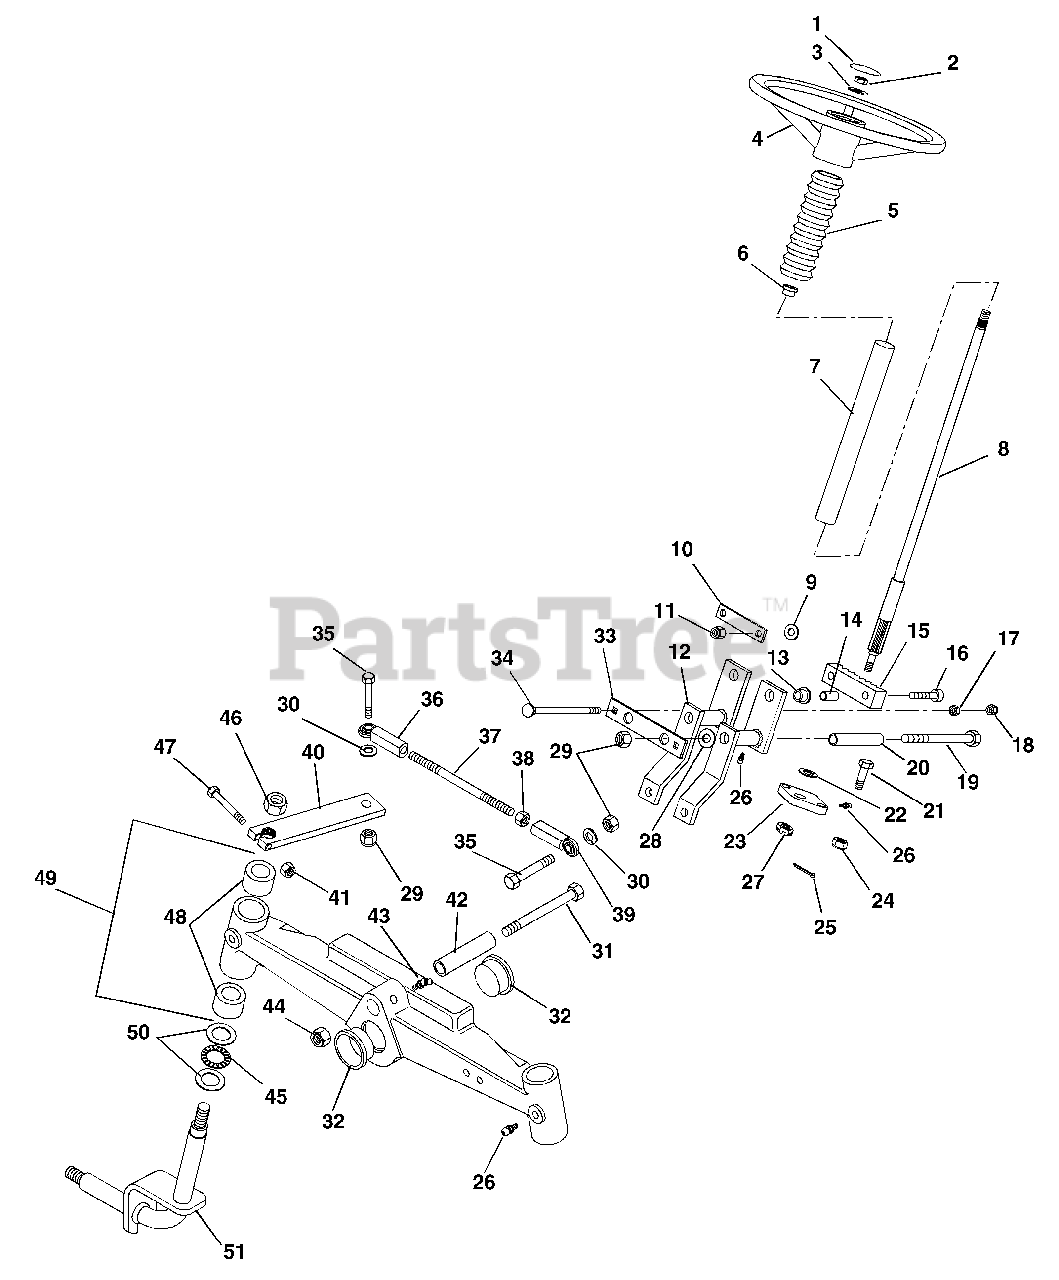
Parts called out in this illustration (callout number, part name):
1	Cap, Steering Wheel
2	Nut-Jam .625-11
3	Washer-Flat-Steel .66 x 1.31 x .095
4	Steering Wheel
5	Boot, Steering Column
6	Bushing-Flange .76 x 1.00 x .58 x 1.48 Nylon
7	Tube, Plastic 1.00 I.D.
8	Weldment, Steering Shaft
9	Washer-Flat-Steel .38 x .88 x .083
10	Strap, Rack and Pinion
11	Nut-Locking-Center .38-16
12	Weldment, Steering Arm
13	Bushing-Flange .63 x .88 x .47 x 1.12
14	Bushing,Steel .39 x .62 x .68 Steel
15	Grade, Rack
16	Bolt-Hex .38-16 x 2.00 Grade 5
17	Nut-Hex .31-18
18	Nut-Locking-Center .31-18
19	Bolt-Hex .50-13 x 6.00 Grade 5
20	Sleeve, Pivot
21	Bolt-Hex .44-14 x 1.50 Grade 5
22	Washer-Thrust .51 x .92 x .031
23	Support, Steering Shaft
24	Nut-Locking-Center .44-14
25	Pin-Cotter .09 x 1.00
26	Fitting-Lube .25-28 x .26
27	Nut-Hex-Slotted .50-13
28	Washer-Hardened-Thrust .76 x 1.25 x .094
29	Nut-Locking-Center .50-13
30	Washer-Locking .50 x .125
31	Bolt-Hex .75-10 x 4.50 Grade 5
32	Cap, Front Axle
33	Plate, Adjustment
34	Bolt-Round Head Square Neck .31-18 x 5.50 Grade 5
35	Bolt-Hex .50-13 x 2.25 Grade 5
36	Rod End, Steering Right Hand
37	Tie Rod, Steering
38	Nut-Jam .50-20 Grade 2
39	Rod End, Steering Left Hand
40	Arm, Tie Rod Axle
41	Nut-Center-Lock .31-24
42	Tube, Axle Pivot
43	Fitting-Lube 45 Degree
44	Nut-Locking-Center .75-10
45	Bearing-Thrust .88 x .43 x .078
46	Nut-Hex .62-11
47	Bolt-Hex .31-24 x 1.75 Gear 5
48	Bushing-Sleeve .87 x 1.00 x 1.00
49	Axle, Steering
50	Washer-Thrust .88 x 1.43 x .032
51	Weldment, King Pin
